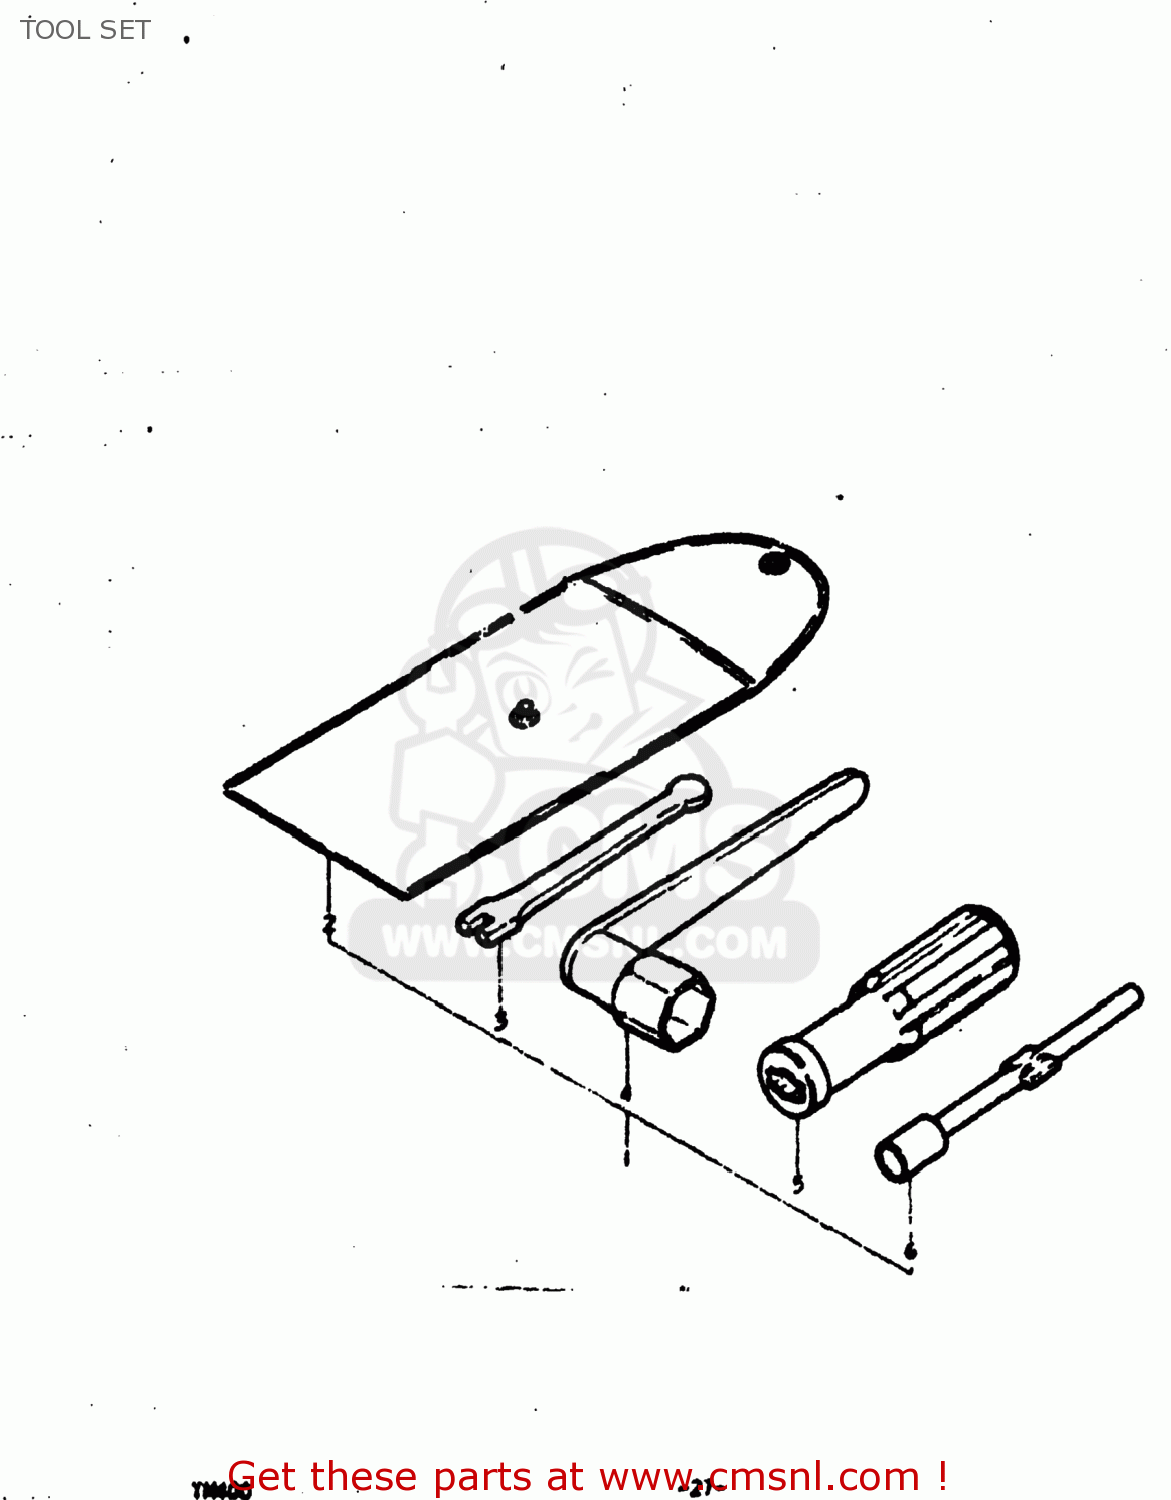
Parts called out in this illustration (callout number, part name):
2	BAG, TOOL R,J,K,L,M
4	SPARK PLUG WRENCH
5	GRIP, SCREW DRIVER R,J,K,L,M
